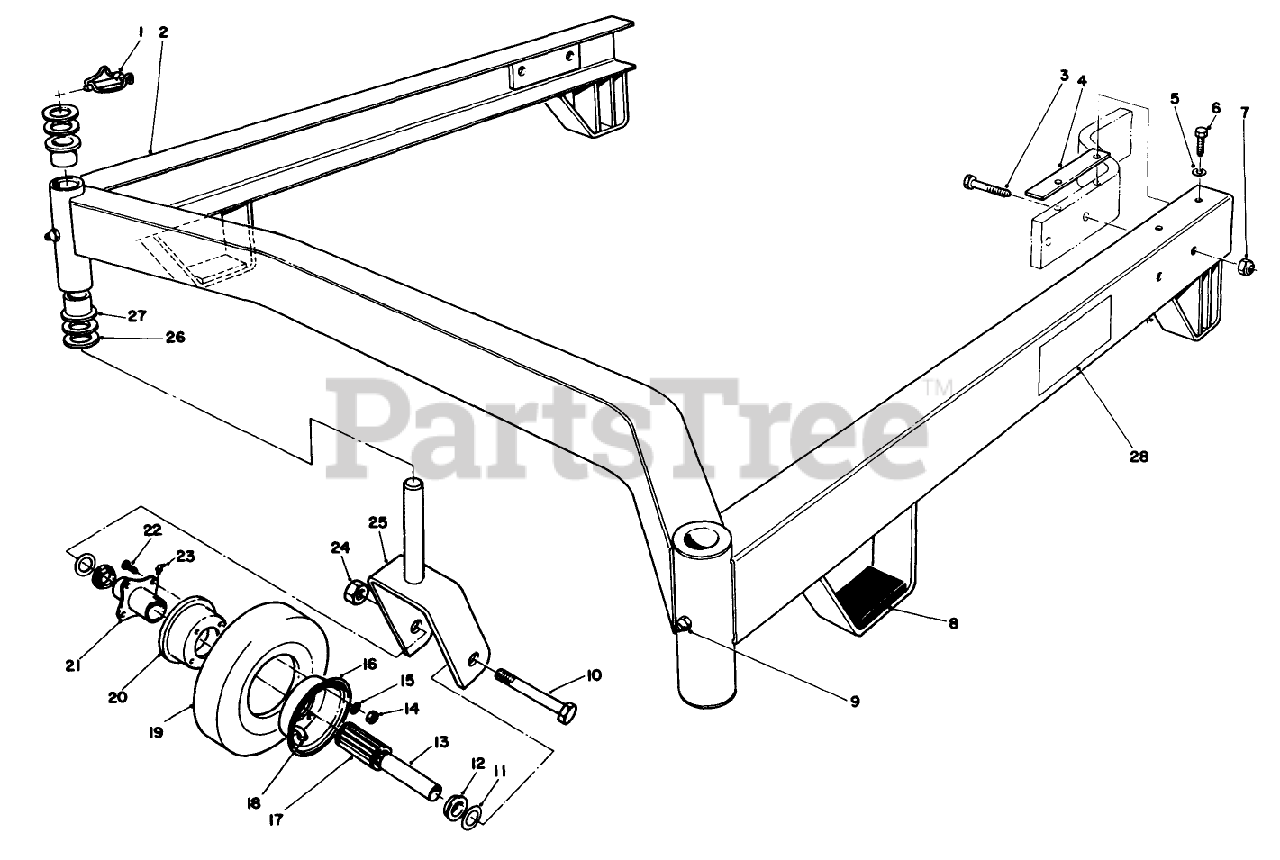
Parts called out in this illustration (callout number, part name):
1	PIN-LYNCH
3	SCREW-HH
4	SHIM-CARRIER
5	WASHER-FLAT
6	SCREW W/PATCH
7	NUT-LOCK, CONE
9	FITTING-GREASE
10	SCREW-HH
11	WHEEL SPACER
12	RETAINER
14	NUT-HEX
15	SCREW-HH
16	WHEEL HALF-MALE
17	ROLLER BEARING
19	TIRE 8"(4-PLY)
20	WHEEL HALF-FEMALE
21	HUB - CENTERED
22	WHEEL BOLT
23	FITTING-GREASE
24	NUT-LOCK
26	WASHER-THRUST
28	DECAL-HOC, LH
